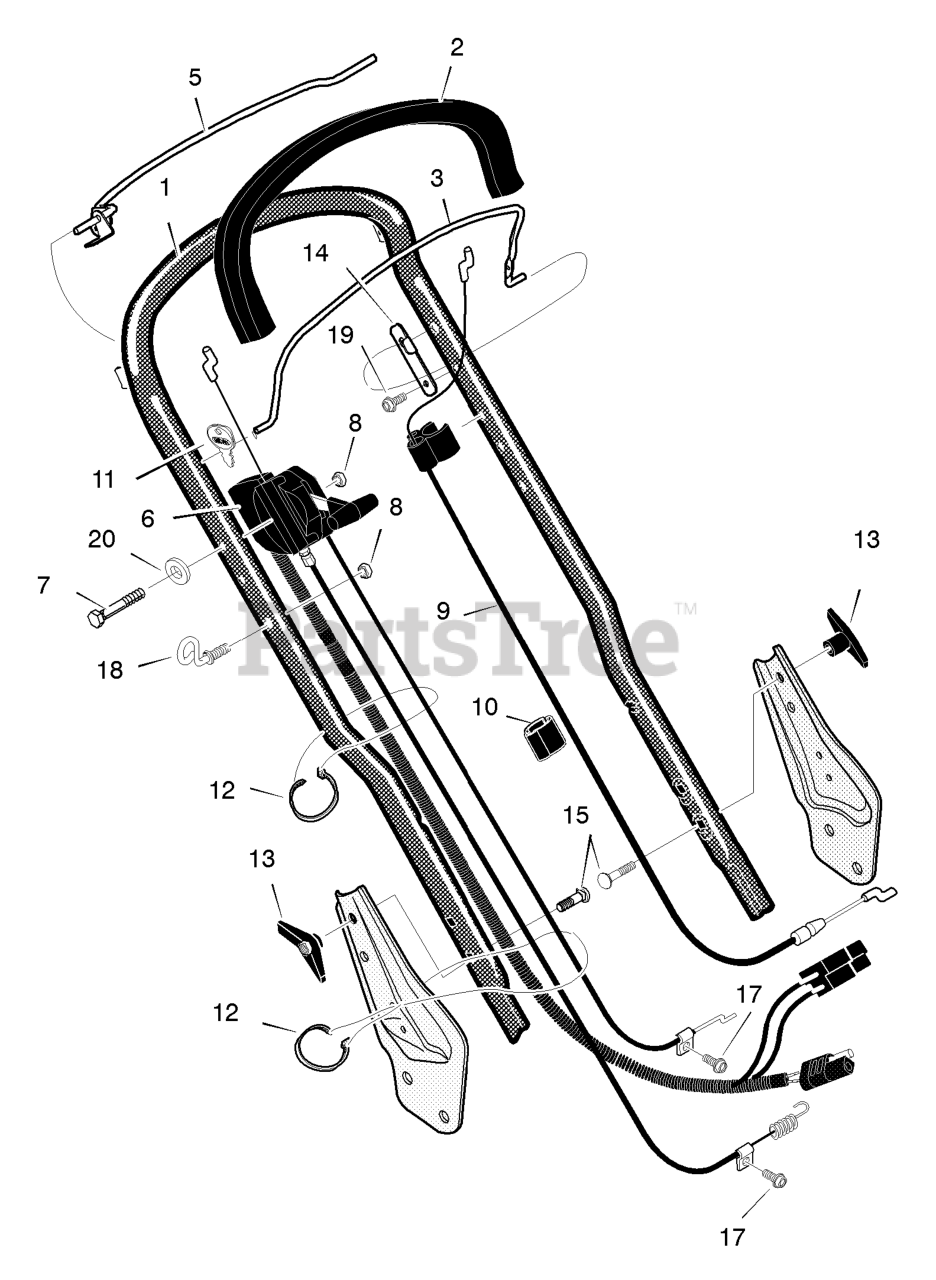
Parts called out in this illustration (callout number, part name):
1	HANDLE, UPPER
2	SLEEVE, HANDLE
3	LEVER, STOP
5	LEVER, DRIVE
6	DRIVE CONTROL & CABLE
8	NUT
9	CABLE, STOP
10	CLIP, CABLE
11	KEYS & RING
12	STRAP, TIE
13	WINGNUT
14	BRACKET, STOP
15	BOLT, CARRIAGE
18	GUIDE, ROPE
19	SCREW
20	WASHER
